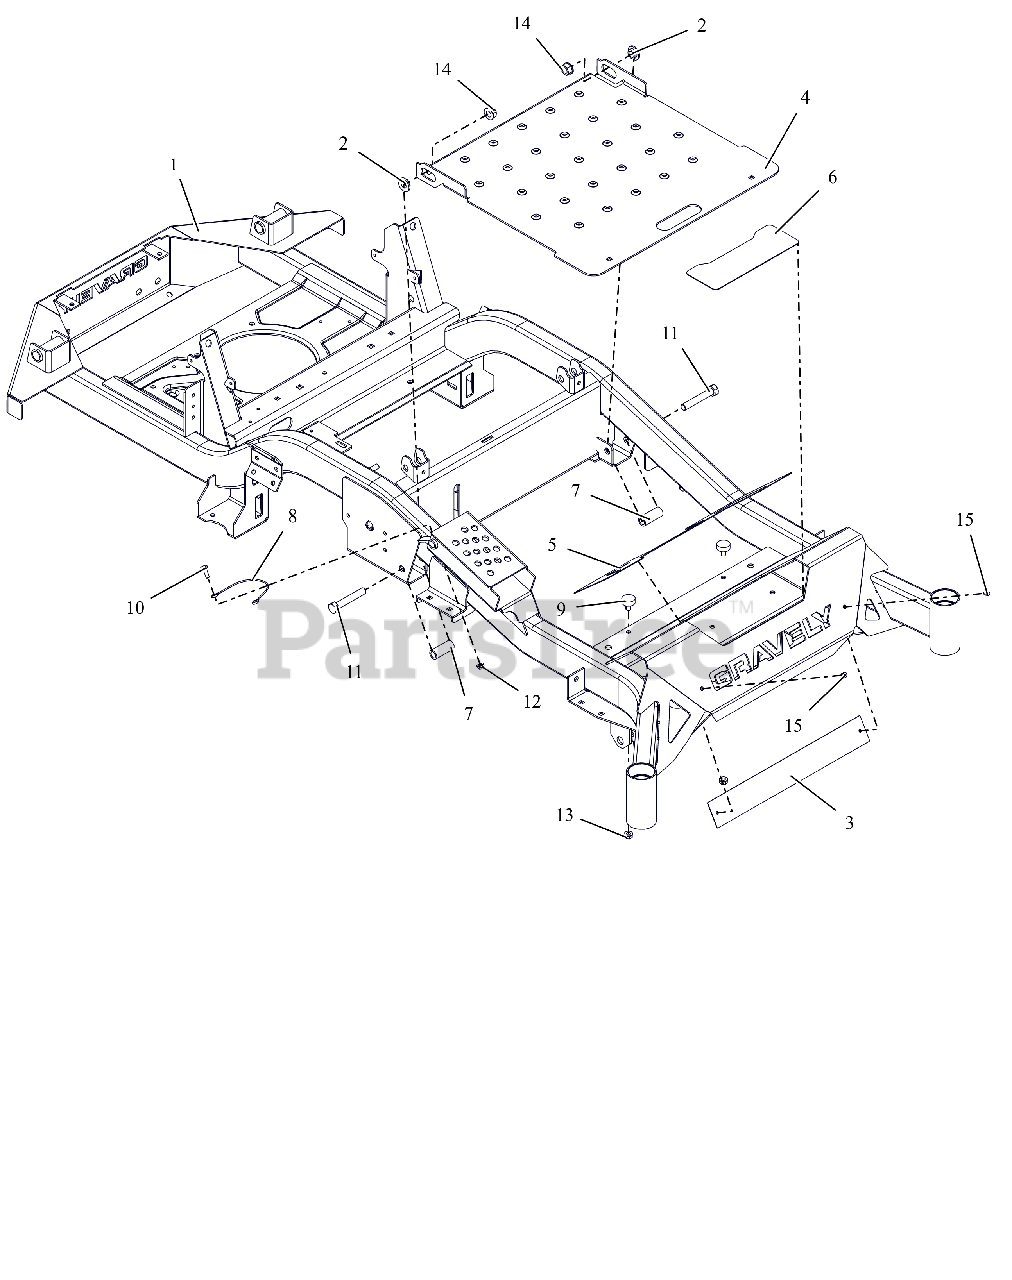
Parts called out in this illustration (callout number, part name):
1	HD 44-52 FRAME W/SAFETY DECALS
2	BSHG-FLG .515X.750X.310X1.120
3	PLATE, BACK FOOT-REST XL
4	KIT,ACCESS PANEL W/DECALS-RED
5	GRIP, FRONT
6	GRIP, STEP
7	SPACER, .515X.75X1.83
8	CABLE, 12.0 LANYARD, NYLON
9	BUMPER, RUBBER
10	BLT, HEX .25-20X.75 G5 ZCC
11	BLT, HEX .50-13X3.00 G5 ZCC
12	NUT,NYL-FLG .25-20 GF ZCC
13	NUT,SPNLK-FLG .31-18 G5 ZCC
14	NUT-LK-TOP-FLG .500-13 GF ZCC
15	RIVET, .1875 AL/AL .126-.250
